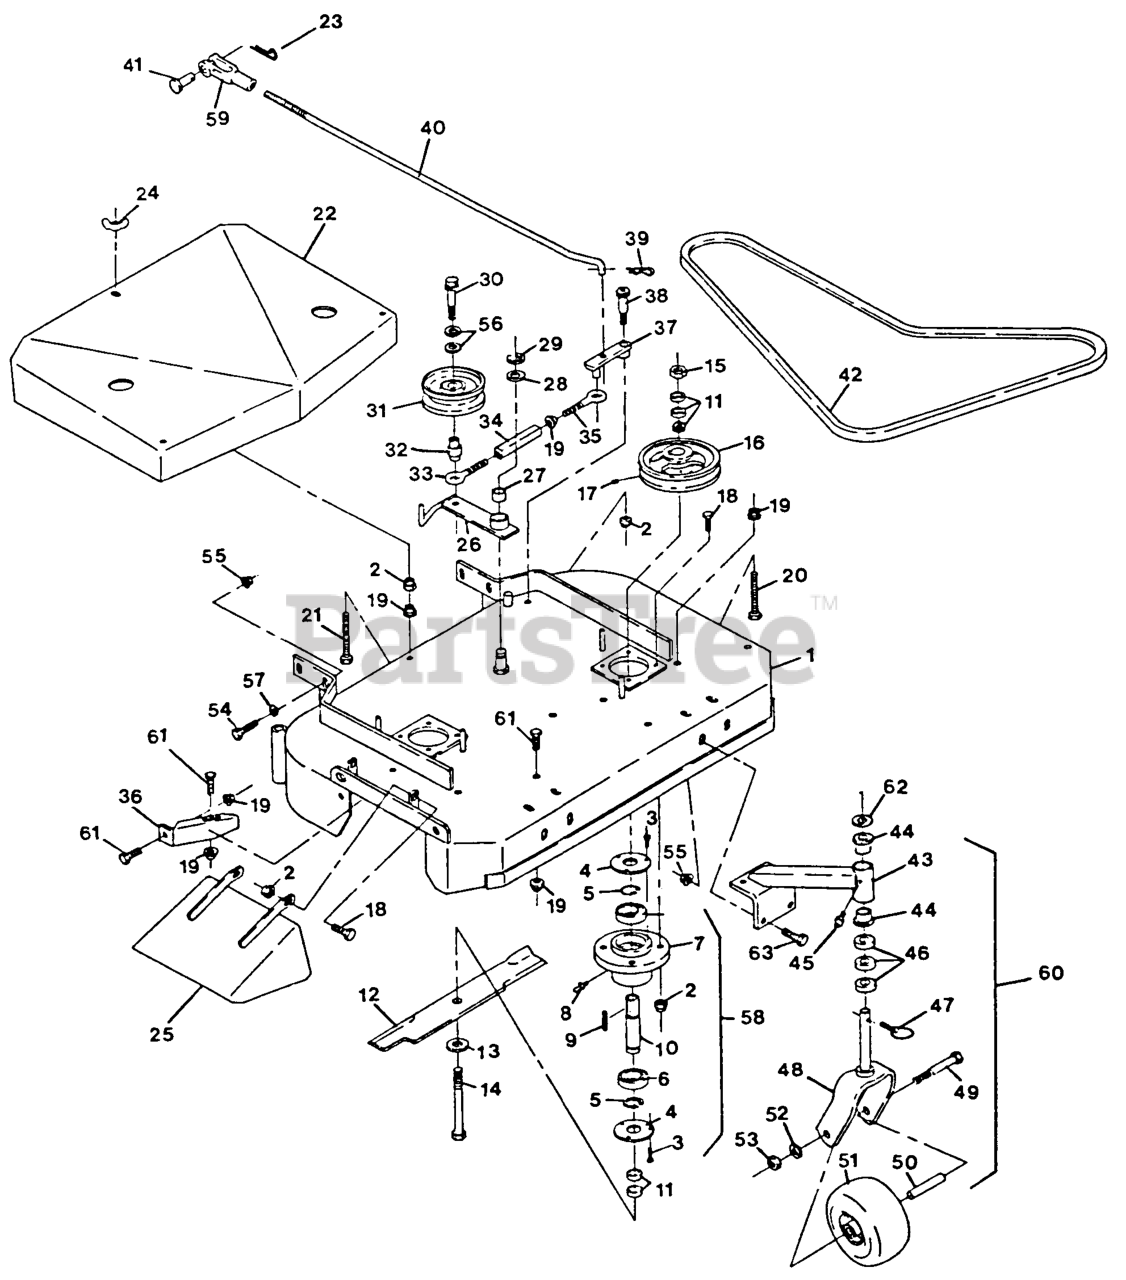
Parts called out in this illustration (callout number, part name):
3	SCRWMACH PHS
4	CAP,CUTTER HOUSING
5	RING,RETNG WLDS 5108-100
7	HOUSING,CUTTER
10	SPINDLE,CUTTER
16	PULLEY,CAST IRON
17	SCREW-SET
20	BOLT,TAP HH
21	BOLTTAP HH
27	BEARING,POWDERED METAL
28	WASHER-SPINDLE
32	BUSHING-ENGAGEMENT
33	EYEBOLT-THREAD, LH
34	BODY-TURNBUCKLE
35	EYEBOLT-THREAD, RH
36	BAFFLE-DOGLEG
38	BOLT,SHLDR KSKH
39	PIN-COTTER
40	ARM-LINKAGE, ASSIST
41	PIN-CLEVIS
42	BELT,DECK DRIVE
44	BEARING-FLANGED
46	SPACER-CASTER
58	HOUSING,CUTTER COMPLETE
59	YOKE-ADJUSTABLE
62	WASHER-FLAT
